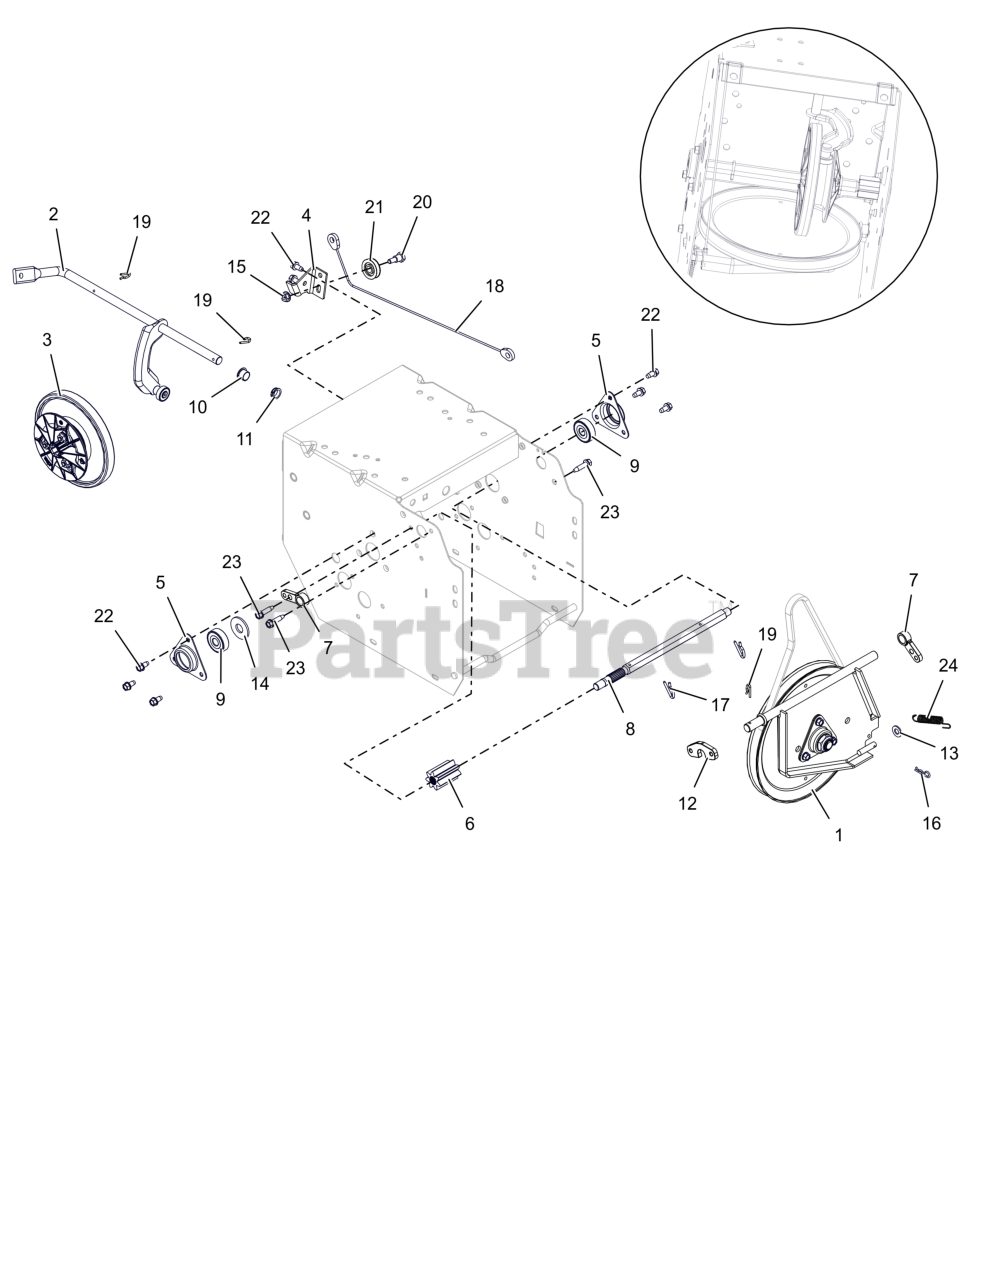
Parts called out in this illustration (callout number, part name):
1	PLATE, SWING - ASSEMBLY
2	ARM, SHIFT-SMALL DASH (ASSY)
3	DISC, FRICTION DRIVE-ASSEMBLY
4	BRKT, CABLE PULLEY
5	FLANGE, BEARING
6	GEAR, PINION 7 TOOTH W/SPLINE
7	SUPPORT BUSHING, SWING GATE
8	SHAFT, HEX W/SPLINE
9	BRG-BALL .437X1.375X.437
10	BUSHING, POLYLINER-.50 SPLIT
11	BUSHING, POLYLINER-.50 SNAPIN
12	SPACER, SWING GATE
13	WSHR,FLT .344X.688X.065 ZCC
14	WSHR,FLT .563X1.375X.109 ZCC
15	NUT-LK-CTR-FLG .25-20 ZC120
16	PIN, HAIR #213 .08X1.19 ZCC
17	PIN, SPRING CLIP
18	CABLE, LOWER TRACTION (CMPCT)
19	CLIP, SPRING
20	BOLT, SHLDR -.375 X .375 X .25-20
21	PULLEY, CABLE
22	SCR-TAP .25-20X.50 HWH ZCC
23	SCR, TAP .25-20X1.00 TT2000 ZCC
24	SPRING, EXT. .043X.438X1.64
